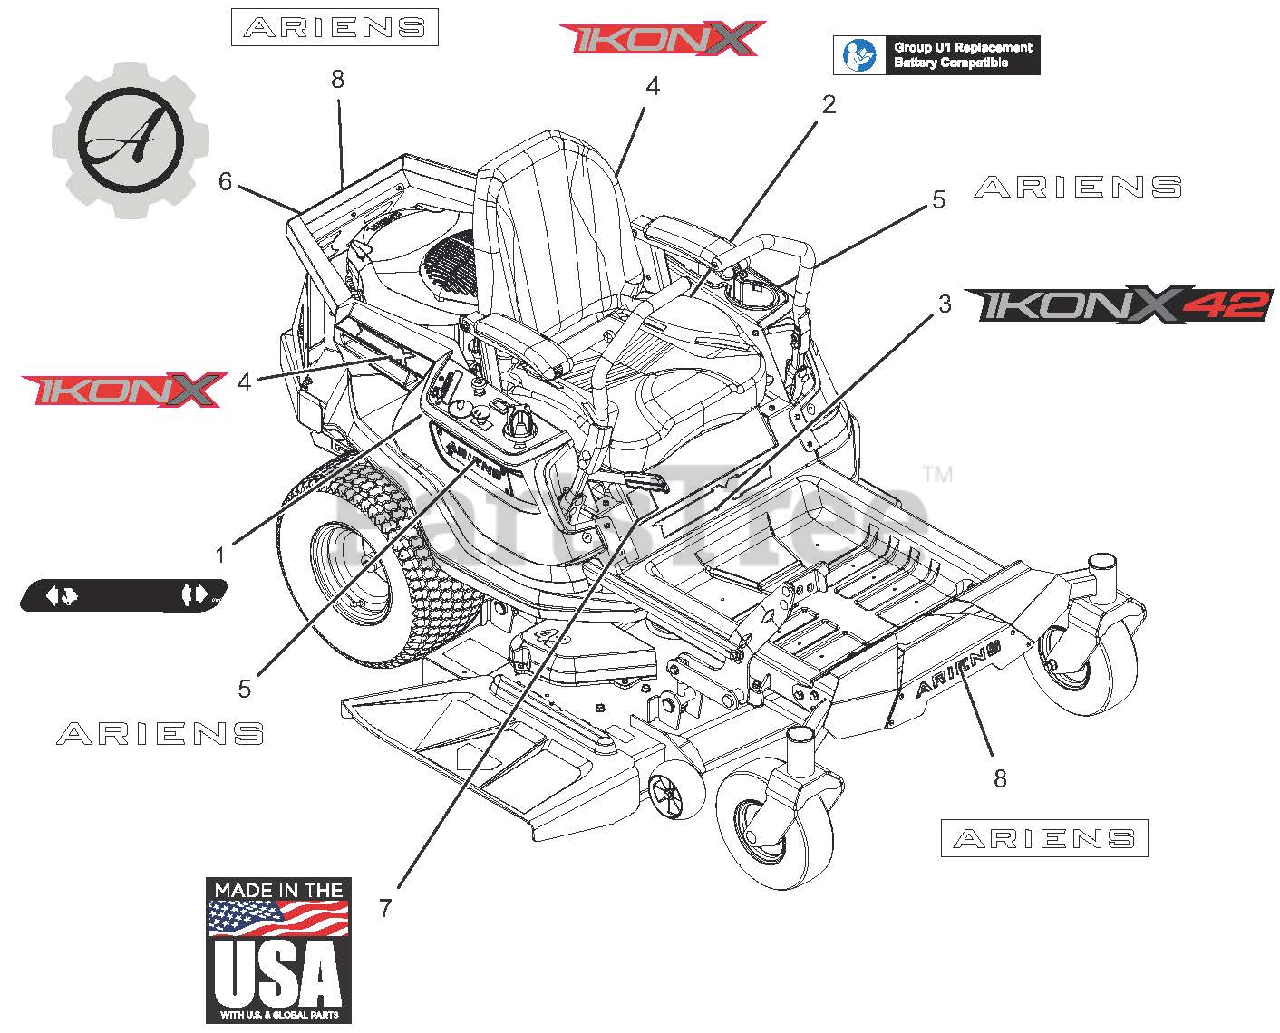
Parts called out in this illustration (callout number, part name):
1	DECAL, DASH DECAL
2	DECAL, U1 BATTERY REPLACEMENT
3	DECAL, IKON-X 42"
4	DECAL, IKON
5	DECAL, ARIENS (6.50")
6	DECAL, ARIENS-GEAR BADGE
7	DECAL, MADE IN USA
8	DECAL - ARIENS 9.625"
